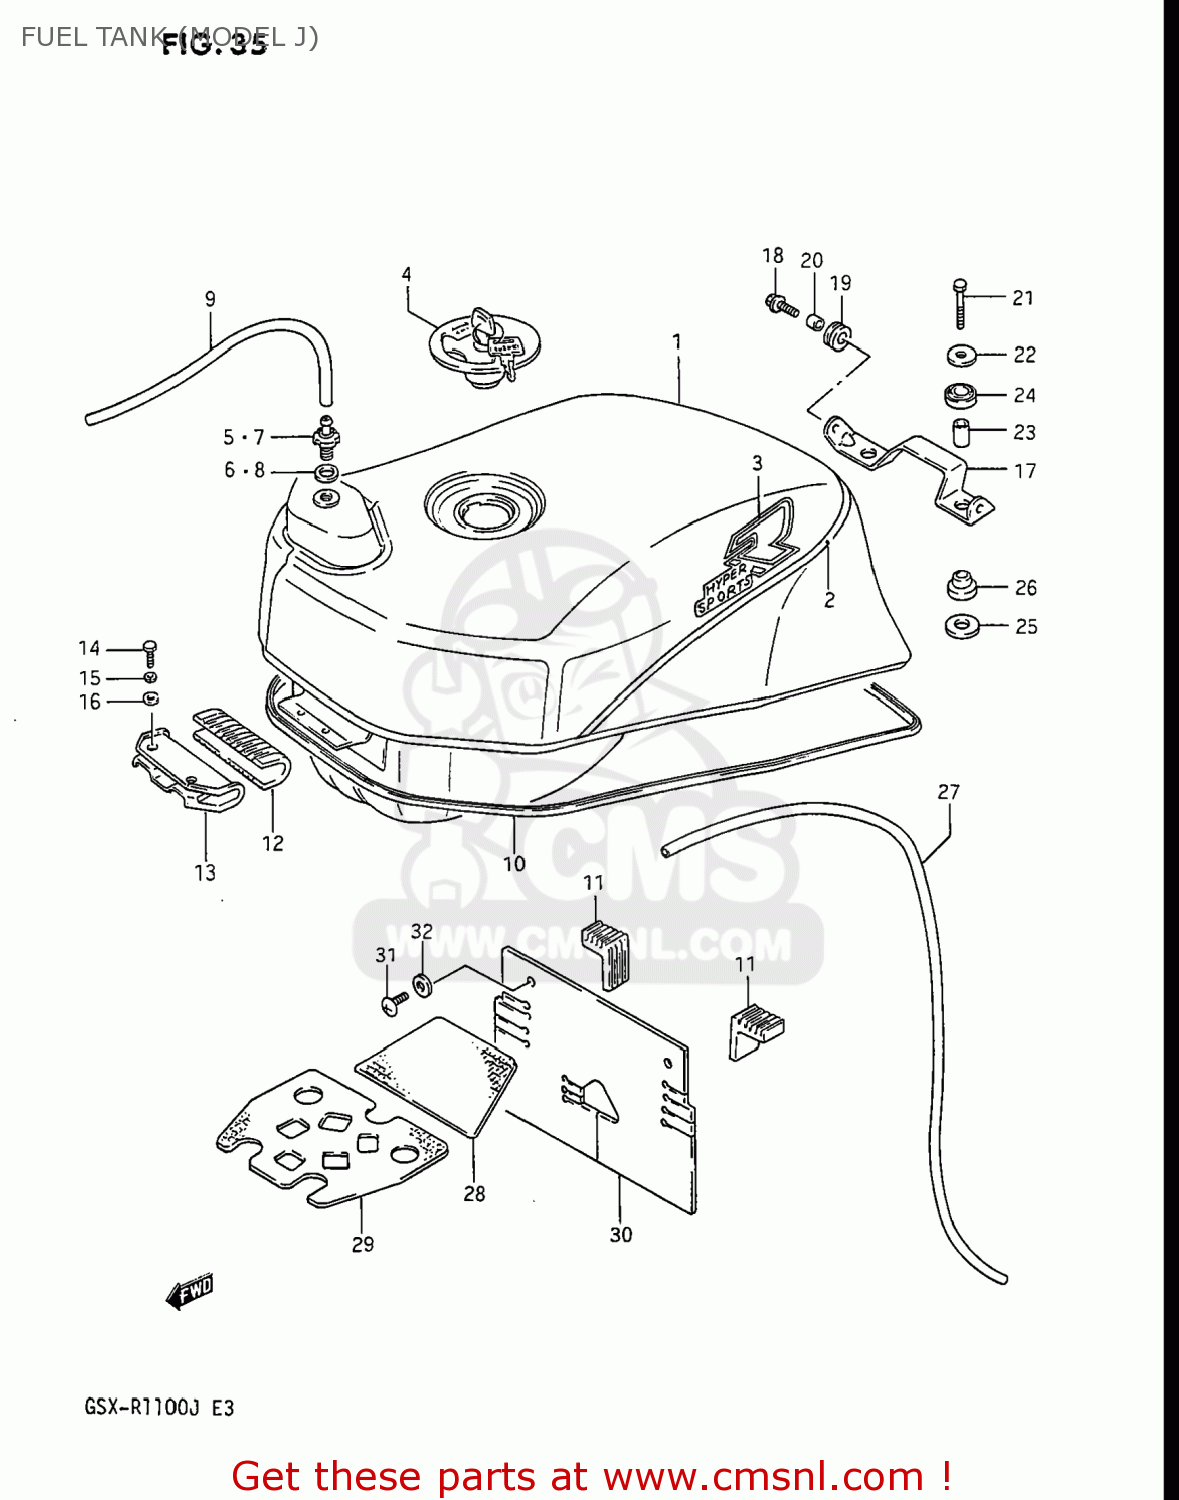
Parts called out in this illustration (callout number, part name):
1	TANK ASSEMBLY,FUEL
2	TAPE,FUEL TANK
3	EMBLEM,FUEL TANK
4	CAP SET,FUEL TANK
5	PLUG,FUEL TANK BREATHER
6	GASKET(12.5X20X2.5) (NAS)
7	(CA) VALVE,FUEL TANK BREATHER
8	GASKET 27X40X2.5 (NAS)
9	HOSE
10	MOLDING,FUEL TANK
11	CUSHION,FUEL TANK SIDE
12	CUSHION,FUEL TANK FR
13	BRACKET,FUEL TANK FR
14	BOLT
15	WASHER,LOCK
16	WASHER
17	BRACKET,SEAT SUPPORT,FRONT
18	BOLT
19	CUSHION
20	SPACER(6.1X9X7.5)
21	BOLT ,6X35
22	WASHER (6.5X24X1.6)
23	SPACER
24	CUSHION
25	WASHER (12.5X24X1.6)
26	CUSHION
27	HOSE
28	SHIELD,FUEL TANK HEAT
29	SHIELD,FUEL TANK HEAT
30	SHIELD,HEAT NO.1
31	SCREW
32	WASHER
